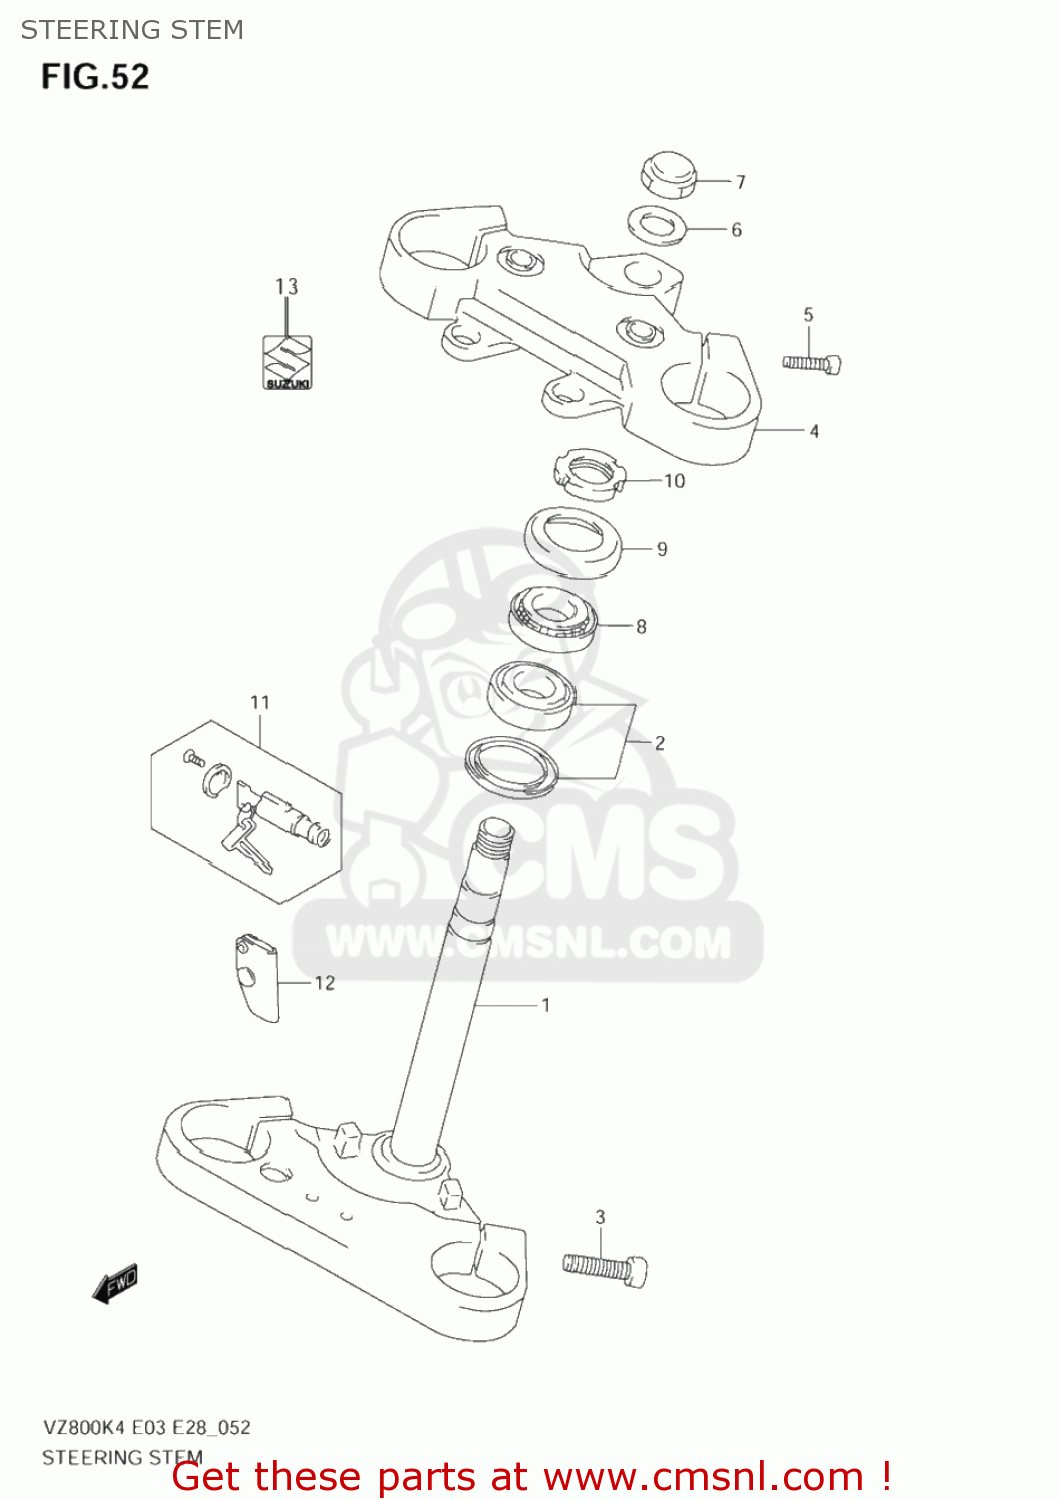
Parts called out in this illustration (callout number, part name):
1	STEM,STEERING
2	BEARING(30X55X17)
3	BOLT,STEM
4	HEAD,STEERING STEM
5	BOLT,STEM HEAD
6	WASHER(22.5X35.9X1.6)
7	NUT,CAP
8	BEARING(25X47X15)
9	SEAL,STEERING UPR DUST
10	NUT,STEERING STEM(25X44X10)
11	LOCK SET,STEERING
12	CASE,STEERING KEY
13	EMBLEM,S
